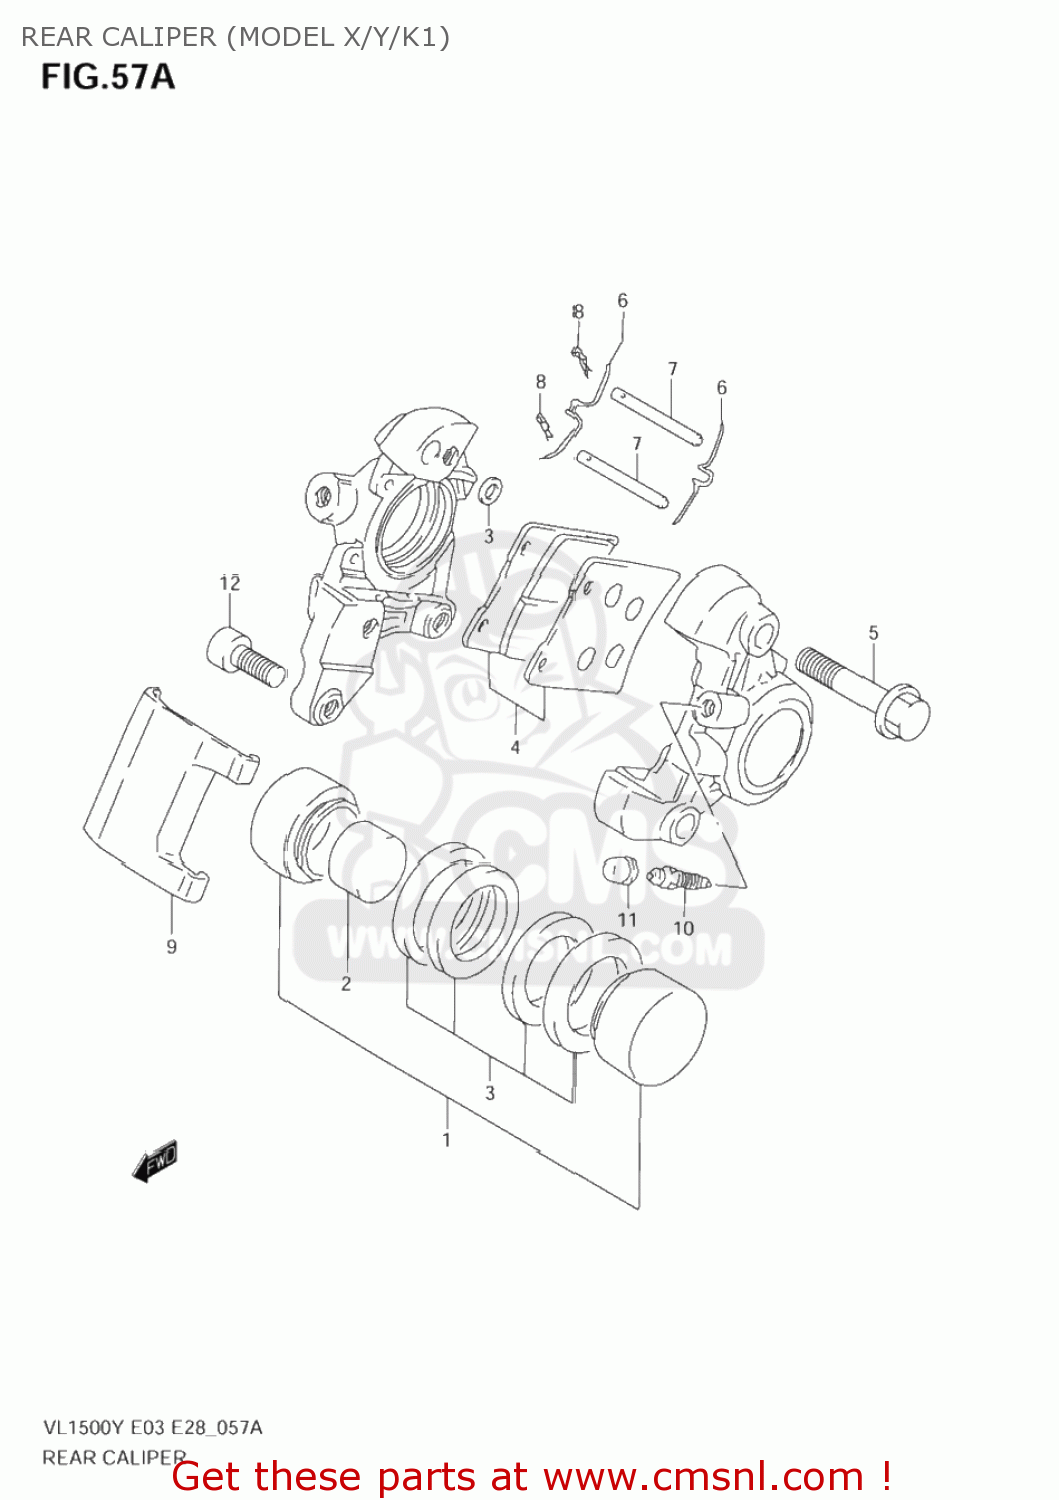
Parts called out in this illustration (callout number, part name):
1	PISTON SET
2	INSULATOR,PISTON
3	SEAL SET,PISTON
4	PAD SET (NAS)
5	BOLT,HOUSING
6	SPRING
7	PIN,PAD
8	CLIP,PAD PIN
9	COVER
10	BLEEDER
11	CAP,BLEEDER PLUG
12	BOLT
